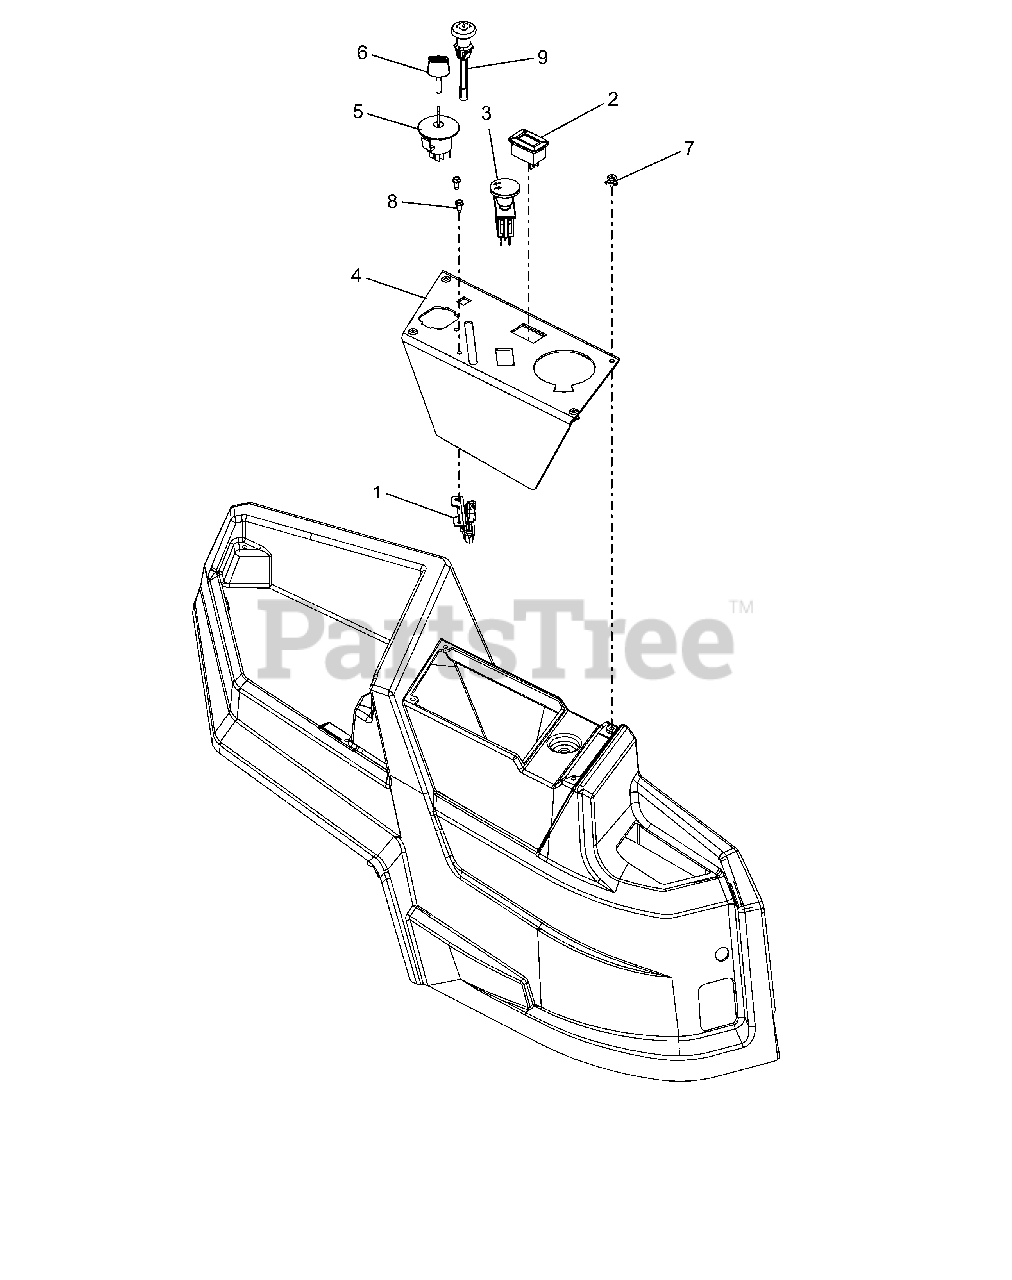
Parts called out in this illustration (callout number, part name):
1	CABLE - THROTTLE CONTROL
2	METER, HOUR W/MAINTENANCE
3	SWITCH, CLUTCH (YELLOW)
4	PANEL, CONTROL
5	KEYSWITCH-IGNITION 4 POS
6	KEY, IGNITION
7	RIVET, PLASTIC .195 DIA.
8	@SCR-TAP 10-24X.50 HWH TR YWZC
9	CABLE - CHOKE, SNAP-IN
